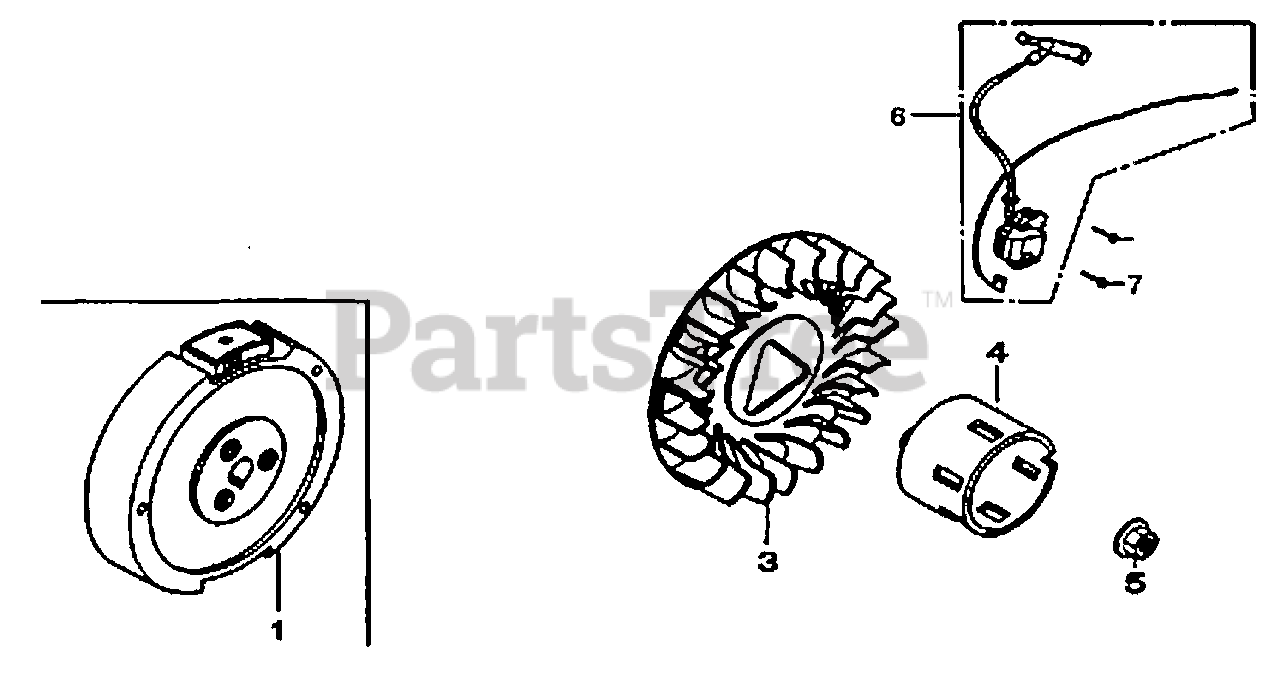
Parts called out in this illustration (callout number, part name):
1	FLYWHEEL COMP.
3	FAN COOLING
4	PULLEY, STARTER
5	NUT SPECIAL, M16
6	COIL ASSY., IGNITION
7	BOLT, FLANGE, M6X25
